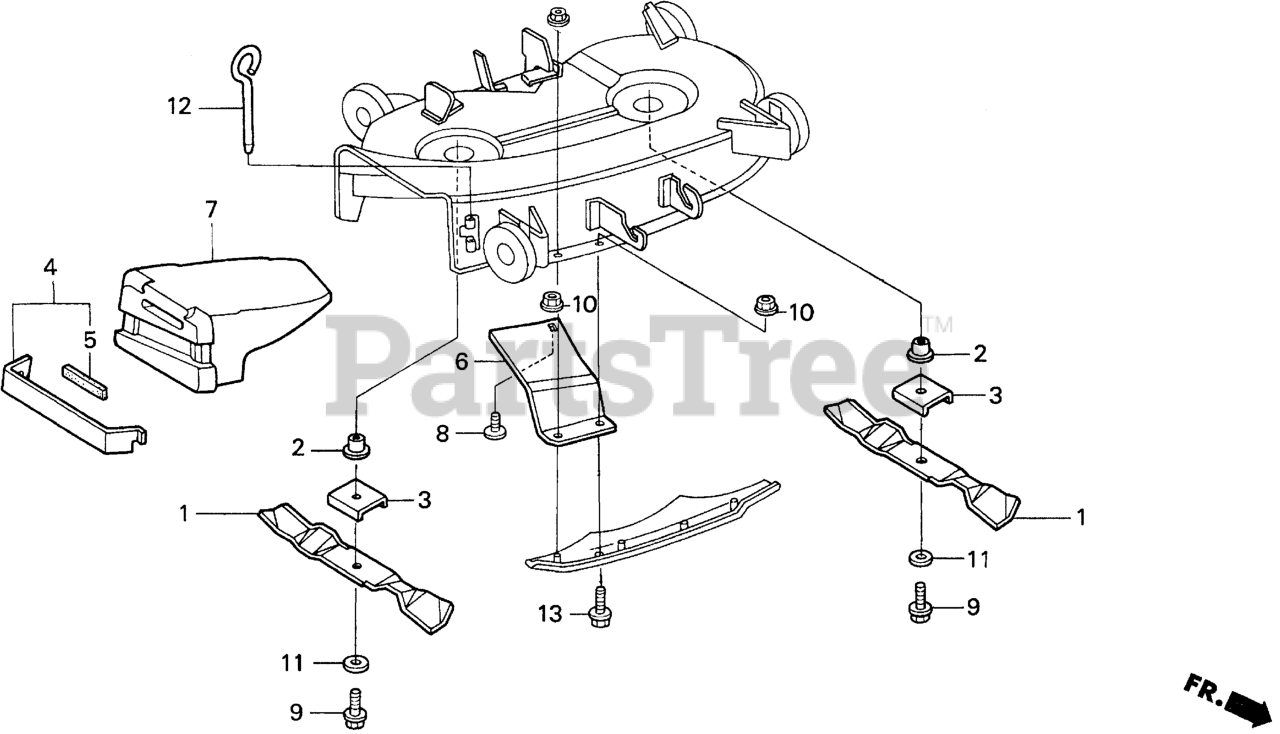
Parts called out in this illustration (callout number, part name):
1	BLADE, ROTARY
2	HOLDER, BLADE
3	HOLDER, BLADE (B)
4	COVER, SWIRL GUIDE
5	SEAL, SWIRL GUIDE COVER
6	GUIDE A, SWIRL
7	GUIDE B, SWIRL
8	BOLT, SPECIAL (9X15)
9	BOLT, BLADE HOLDER (10X28)
10	NUT, FLANGE (8MM)
11	WASHER, BLADE
13	BOLT, FLANGE (8X22) Use from Engine SN 1609607.
